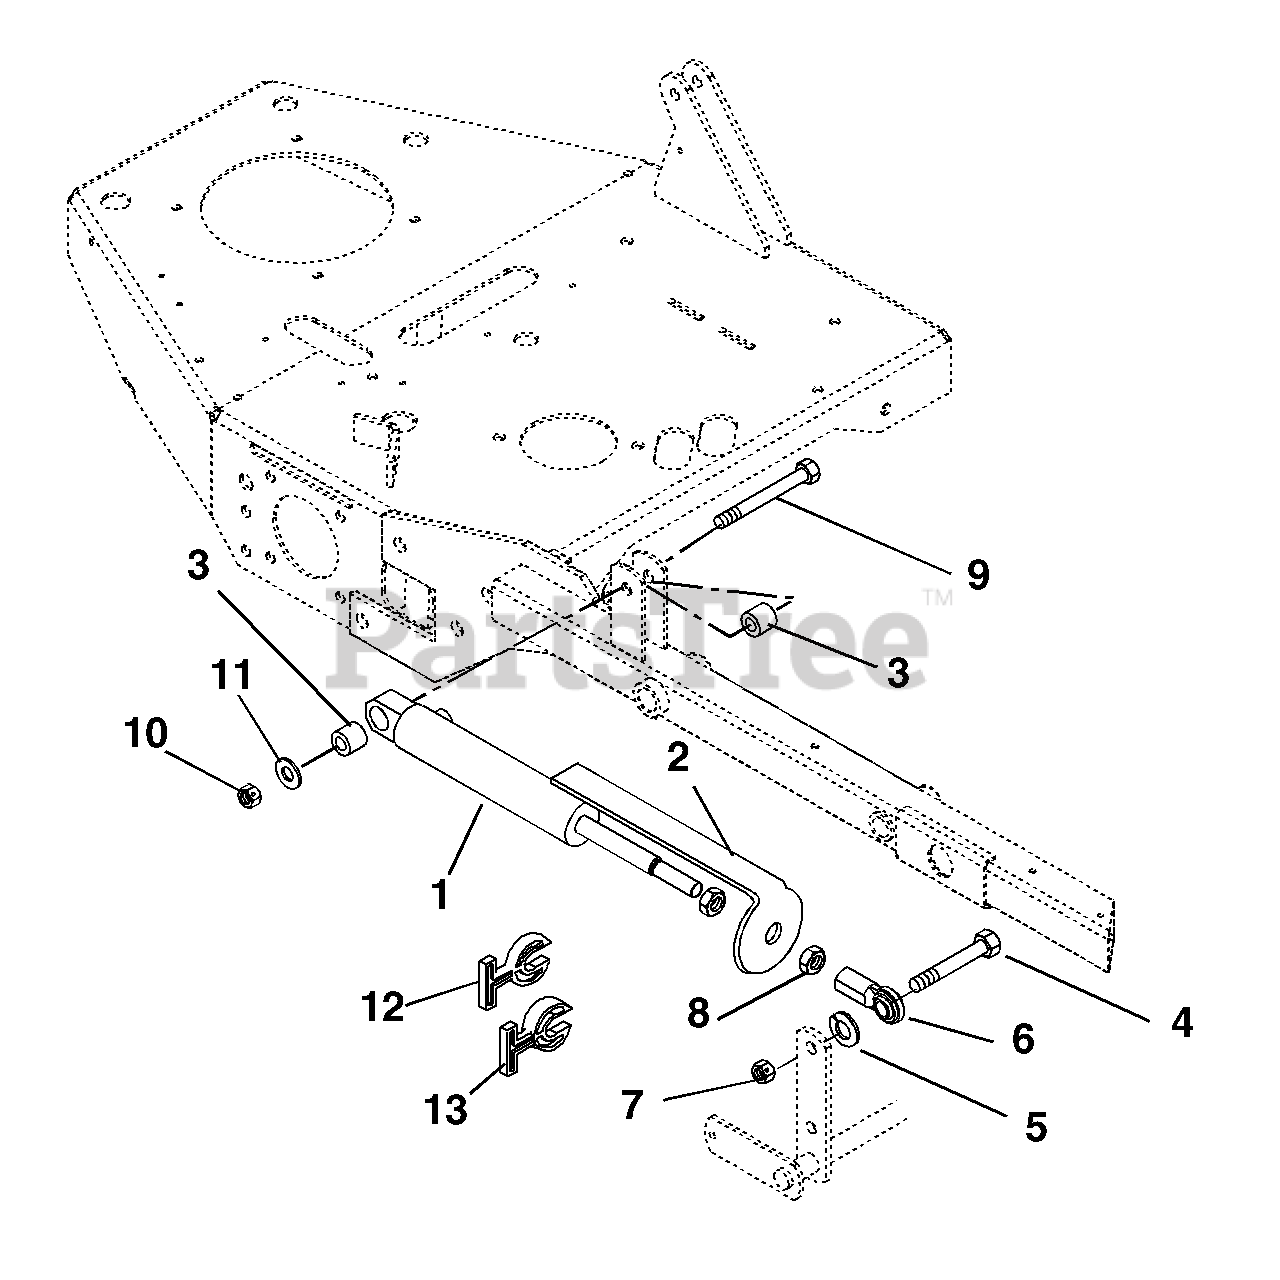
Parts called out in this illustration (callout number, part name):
1	Cylinder-Hydraulic Lift
2	Strap-Height of Cut Indicator
3	Bushing .516 x 1.00 x 1.05
4	Bolt-Hex .62-11 x 2.25 Grade 8
5	Washer-Lock .62 x .156
6	Rod End-Right Hand-Female .63
7	Nut-Locking-Center .62-11
8	Nut-Jam .63-18
9	Bolt-Hex .50-13 x 3.75 Grade 5
10	Nut-Locking-Center .50-13
11	Washer-Flat-Steel .515 x 1.625 x .25
12	Stop, Cylinder .34 Thick
13	Stop, Cylinder .68 Thick
